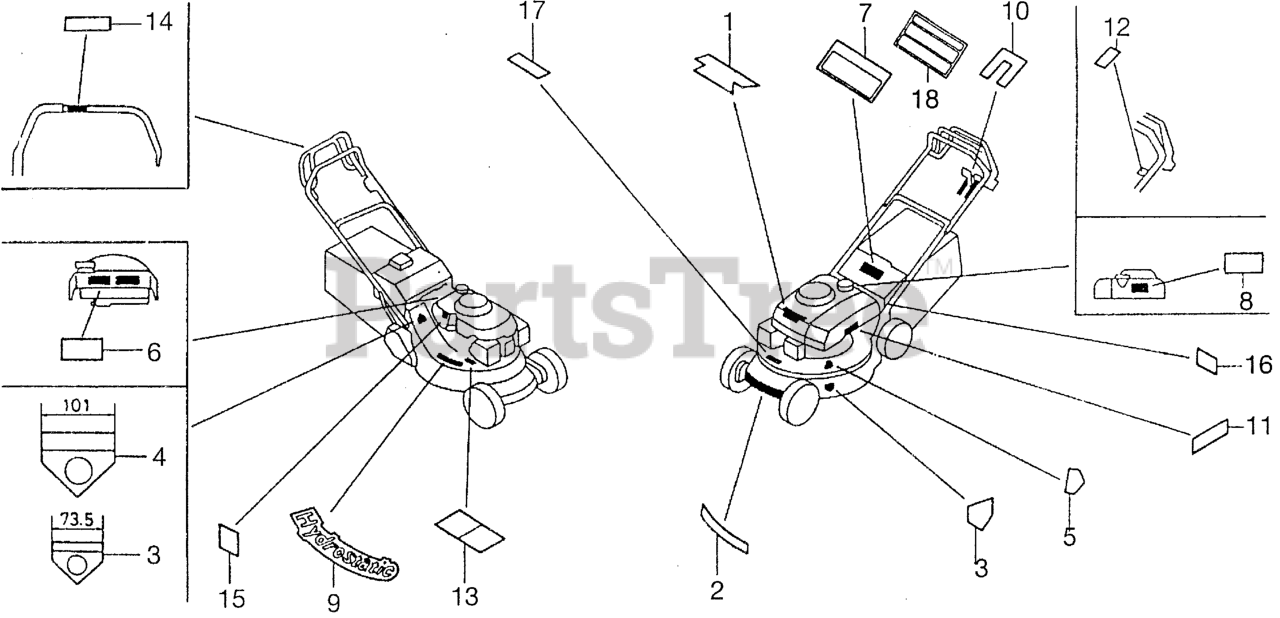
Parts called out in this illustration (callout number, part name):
1	MARK, EMBLEM
2	LABEL A, HOUSING CAUTION (ENGLISH)
3	LABEL C, HOUSING CAUTION
4	LABEL C, HOUSING CAUTION
5	LABEL, STEP POSITION (ENGLISH)
7	LABEL, WARNING (ENGLISH)
8	LABEL, FUEL WARNING (B)(ENGLISH)
10	MARK, THROTTLE INDICATION (ENGLISH)
11	MARK, AIR CLEANER CAUTION (ENGLISH)
14	MARK, BLADE CONTROL (ENGLISH)
15	MARK, OIL CAUTION
16	MARK, TYPE (SXA)
17	MARK, TYPE (SX)
